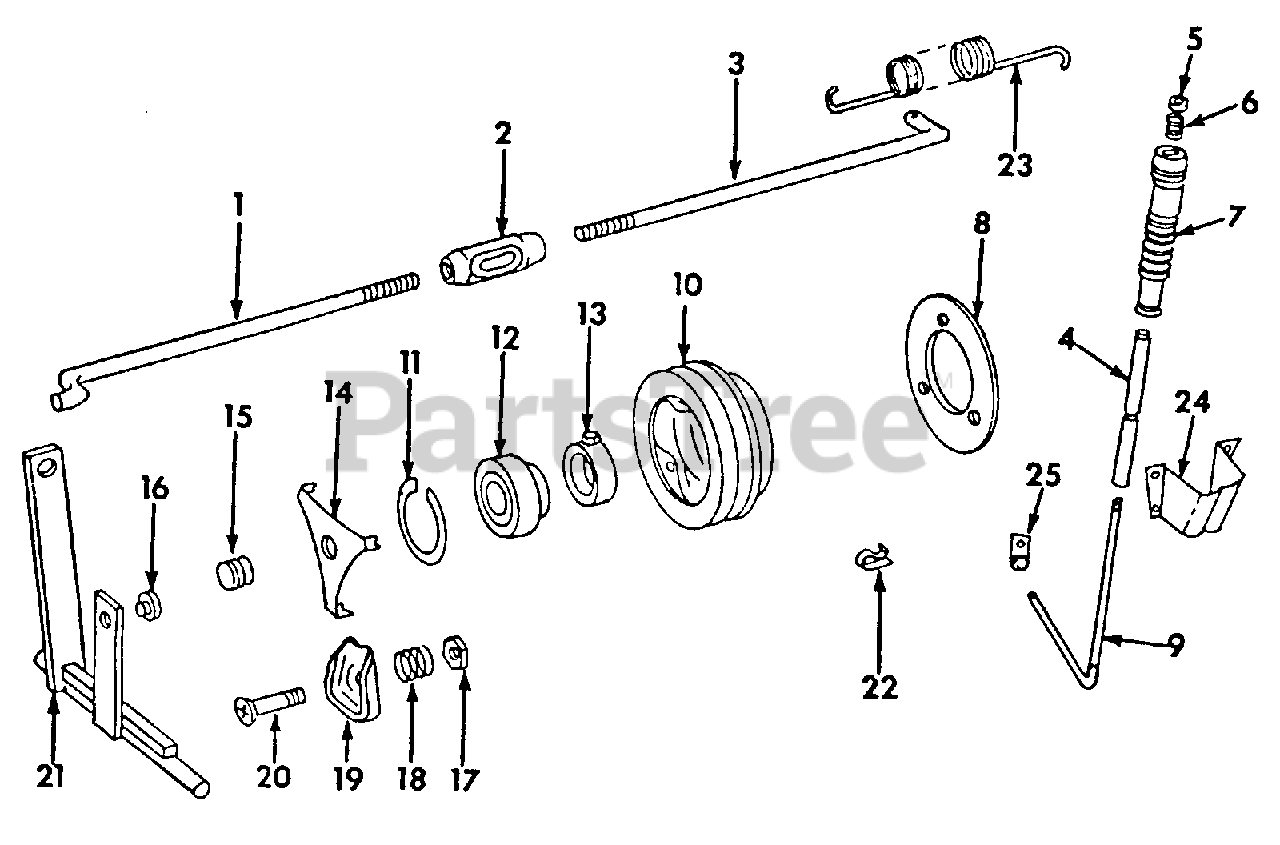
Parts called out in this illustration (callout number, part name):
2	Turnbuckle, Rod
3	Rod, Rear Clutch
5	Spacer, Handle
6	Spring, Handle Return
7	Grip, Handle
8	Plate, Pressure
9	Rod, PTO Control
10	Pulley, Mower Actuating
11	Ring, Snap 2.197 O.D., For Pulley
12	Bearing, Ball
13	Collar w/Set Screw & Lock Nut, Brg
14	Spring, Friction Disc
15	Button, Thrust
16	Button, Wear
17	Nut, 1/4-28 Hex Jam
18	Spring, Compression
19	Lever, Throw-Out
20	Screw, Special Machine
21	Shaft Assy, Clutch
22	Spring, Double Disc
23	Spring, Brake Return
24	Bracket Assy, PTO Handle
25	Lever Assy, PTO
